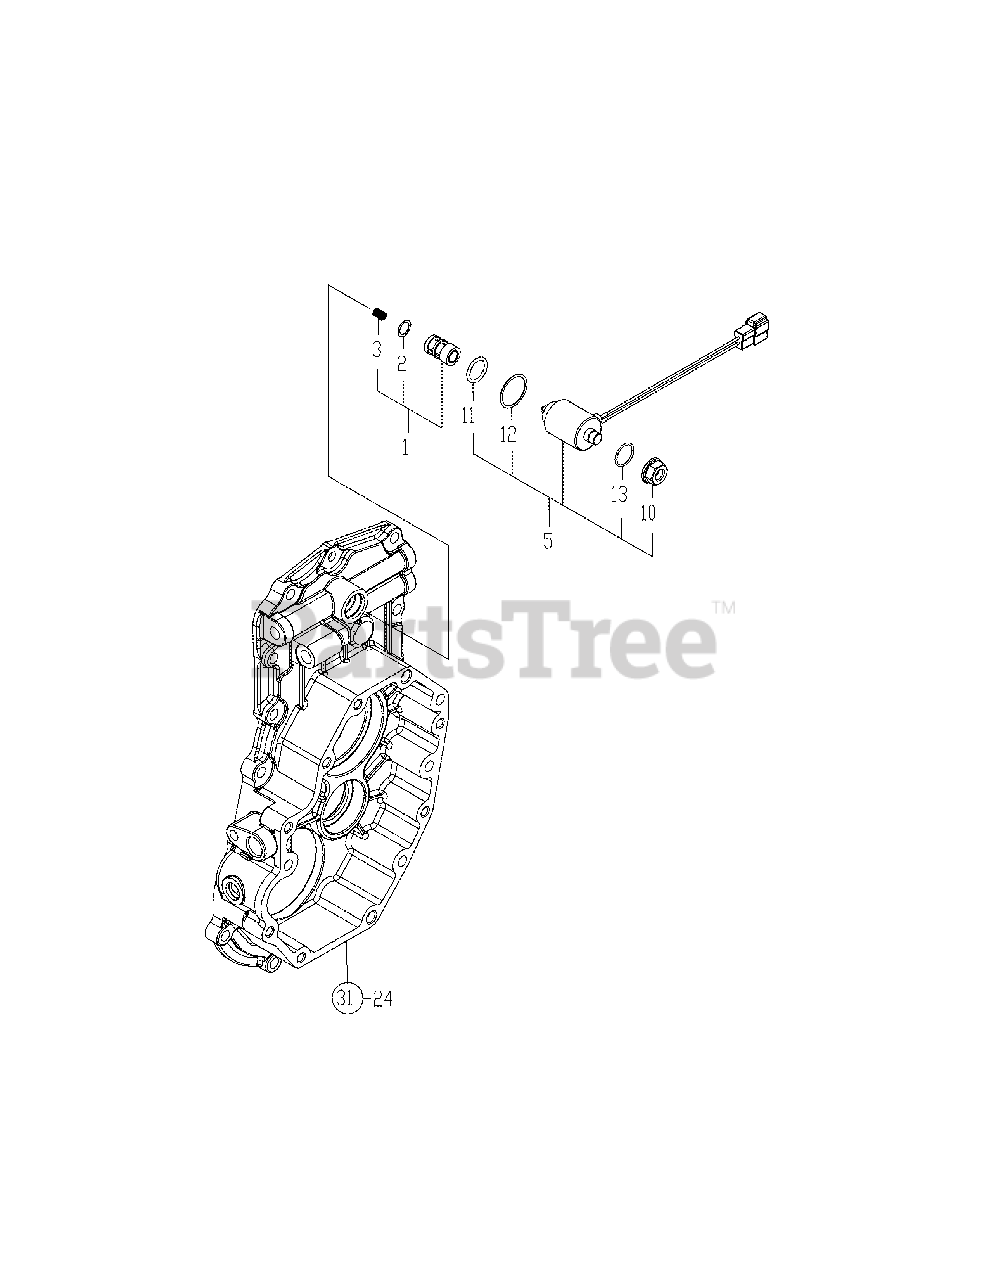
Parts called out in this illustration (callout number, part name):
1	Valve Assy, Solenoid
3	Spring, Solenoid
11	Packing, P 18.0
12	Gasket, Solenoid
13	Packing, S 11.2
